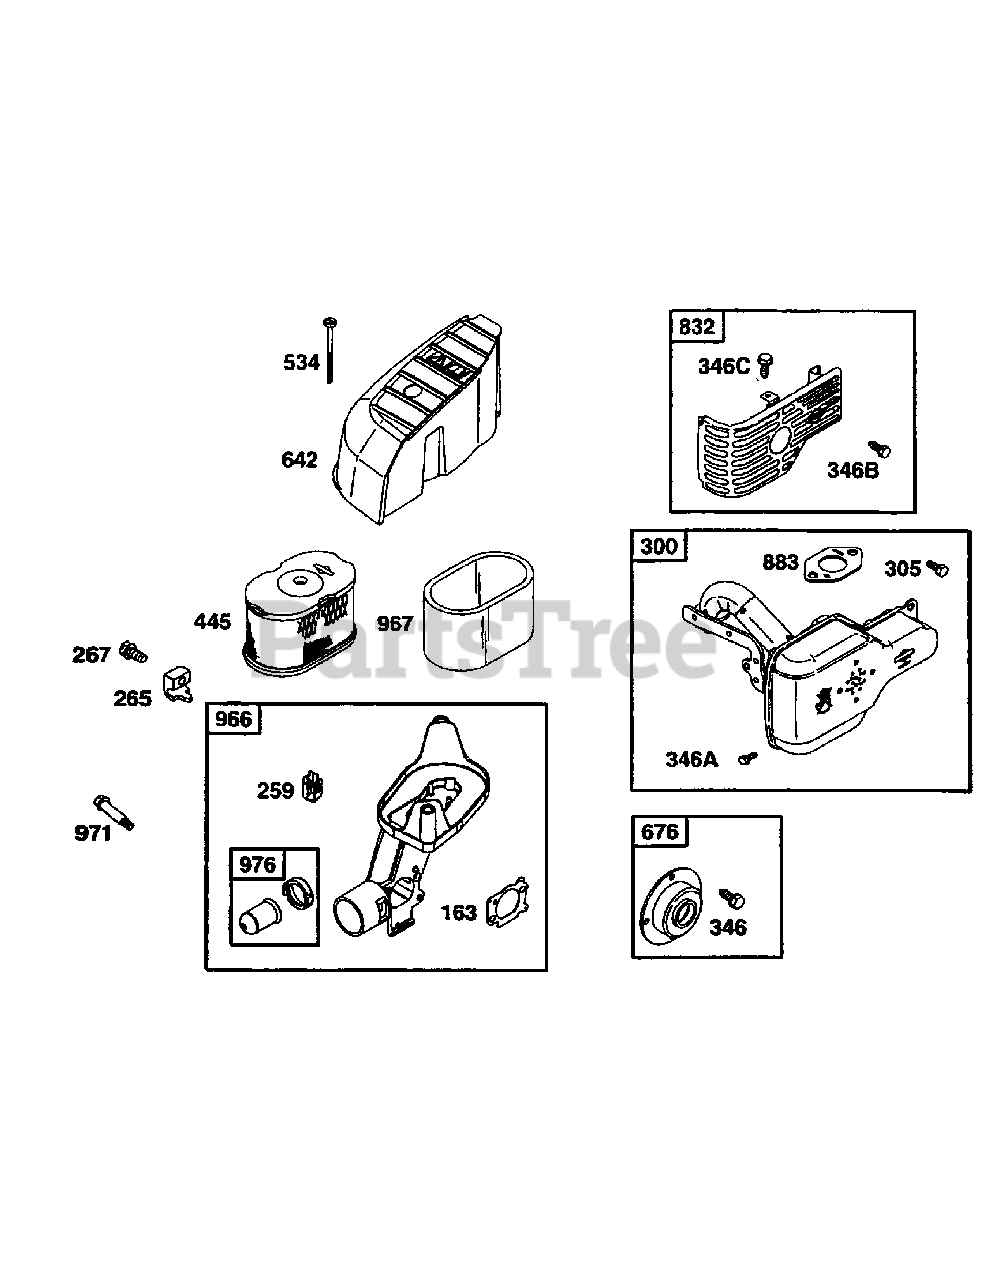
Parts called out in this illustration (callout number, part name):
163	Air Cleaner Gasket
259	Casing Clamp Bracket
265	Casing Clamp
267	Slotted Hex Screw
300	Muffler
305	Hex Screw
346	Hex Screw
346A	Hex Screw
346B	Hex Screw
346C	Hex Screw
445	Air Filter
534	Shoulder Screw
642	Air Cleaner Cover
676	Muffler Deflector
832	Muffler Guard
883	Exhaust Gasket
966	Air Cleaner Base
967	Pre Filter
971	Shoulder Screw
976	Carb Primer
